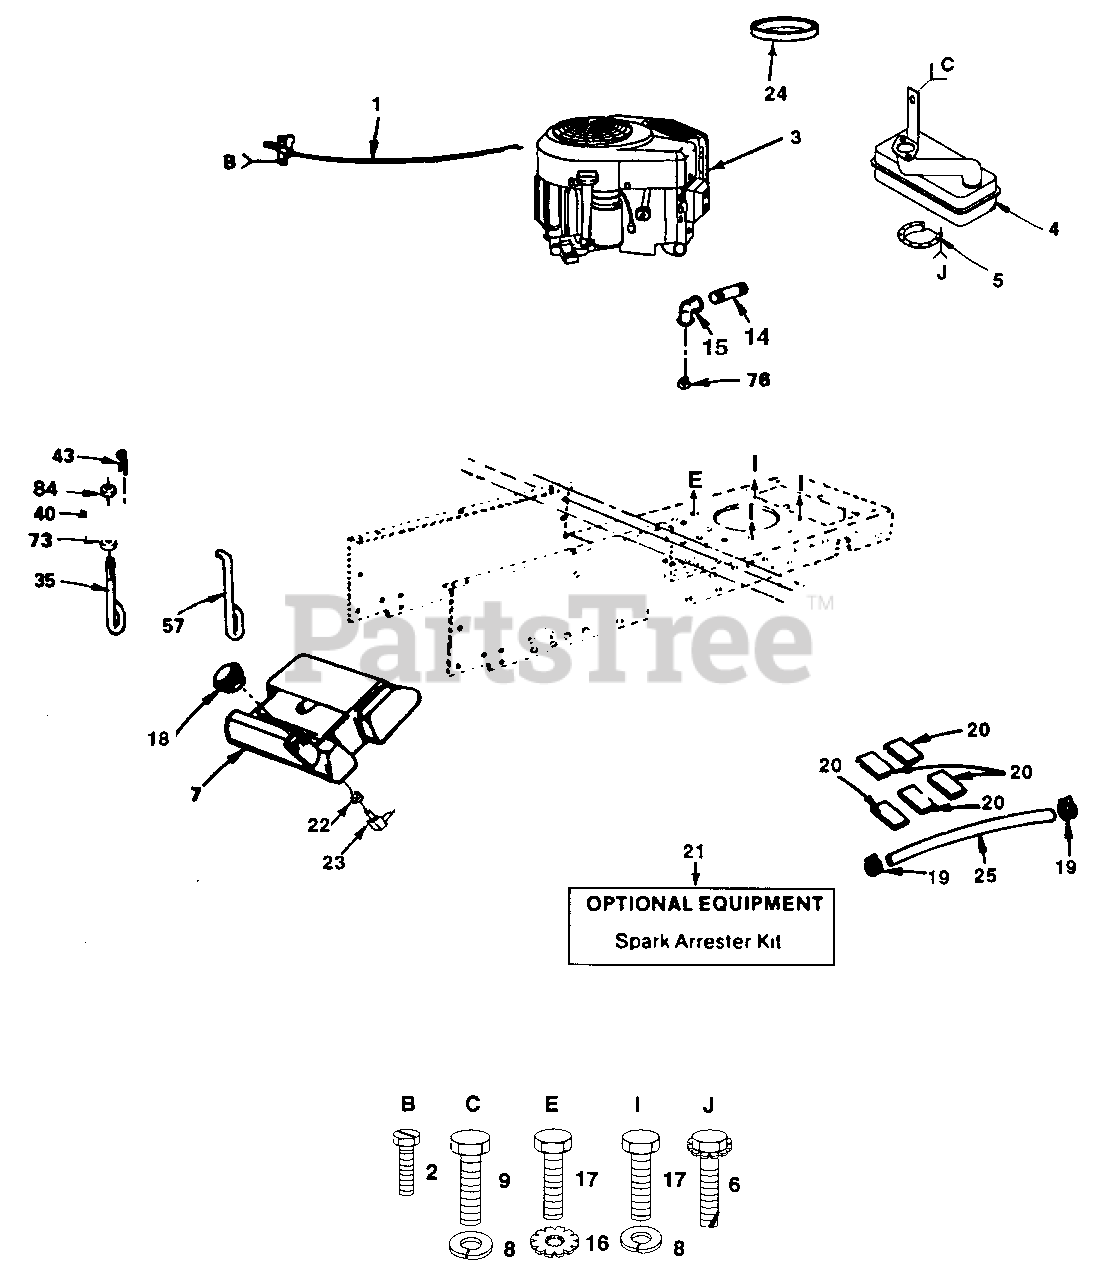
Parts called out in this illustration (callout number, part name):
1	Control, Throttle (AYP part number)
2	Screw, Hex Thread Cut 1/4-20 x 5/8 (AYP part number)
3	Engine Kohler
4	Muffler (AYP part number)
5	Deflector, Muffler (AYP part number)
6	Screw, Spider Lock, Hex Head #8 x 1/2 AB (AYP part number)
7	Tank, Fuel (AYP part number)
8	Washer, Lock Heavy Helical Spring (AYP part number)
9	Bolt, Hex Head 5/16-18 UNC x 1/2 (AYP part number)
14	Pipe Nipple, Standard (AYP part number)
15	90ø Elbow 3/8 NPT (AYP part number)
16	Washer, Lock External Tooth (AYP part number)
17	Screw M8 x 1.25 x 25 mm
18	Cap, Fuel (AYP part number)
19	Clamp, Hose (AYP part number)
20	Pad, Spacer (AYP part number)
21	Spark Arrester Kit (AYP part number)
22	Bushing (AYP part number)
23	Stem, Tank, Fuel (AYP part number)
24	Strip, Foam (AYP part number)
25	Line, Fuel (AYP part number)
